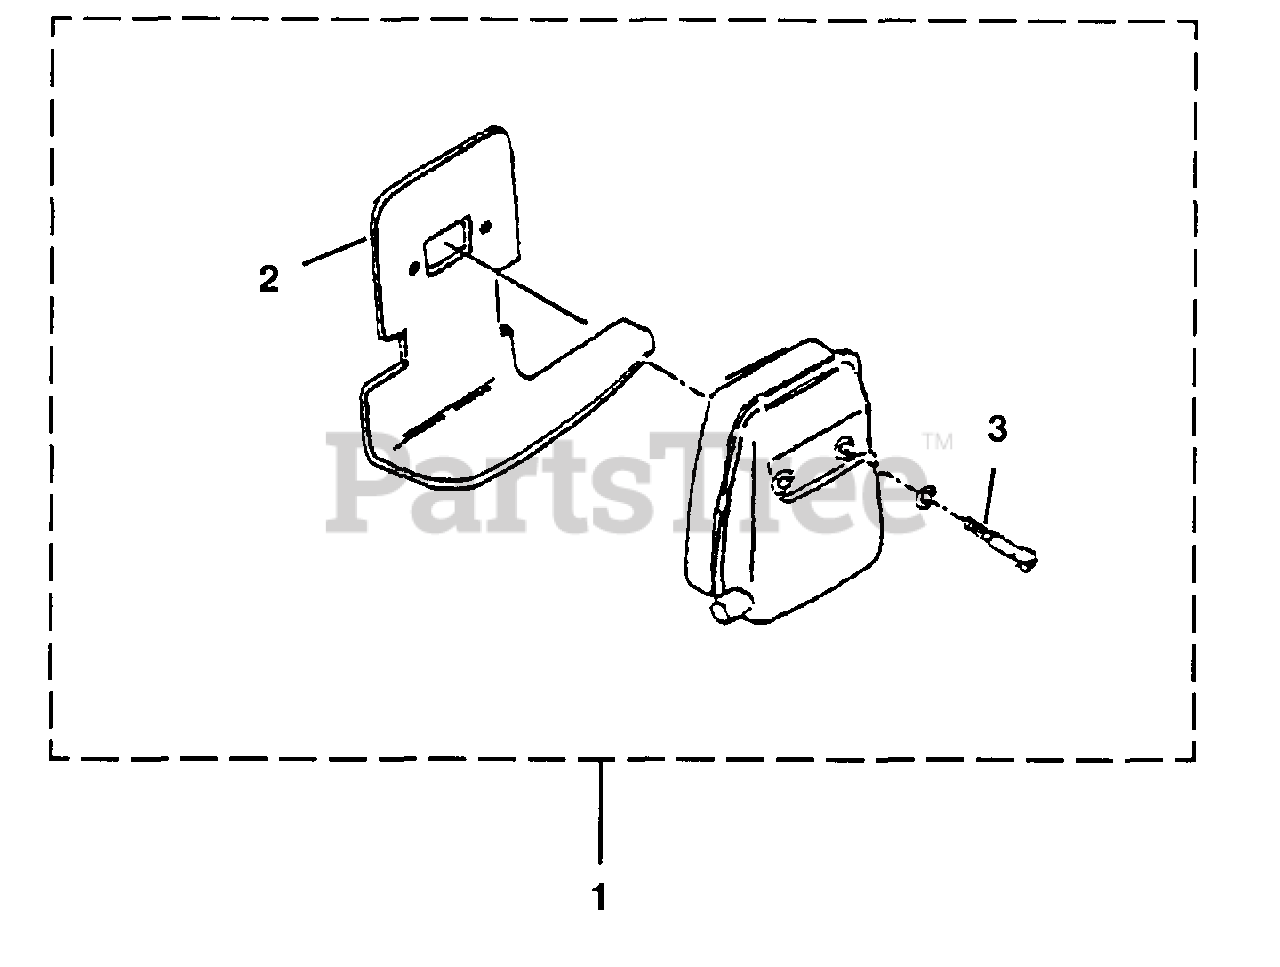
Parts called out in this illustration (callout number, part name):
1	MUFFLER ASSEMBLY
2	GASKET-Muffler
3	SCREW-Socket Hd (M5 x 45)
